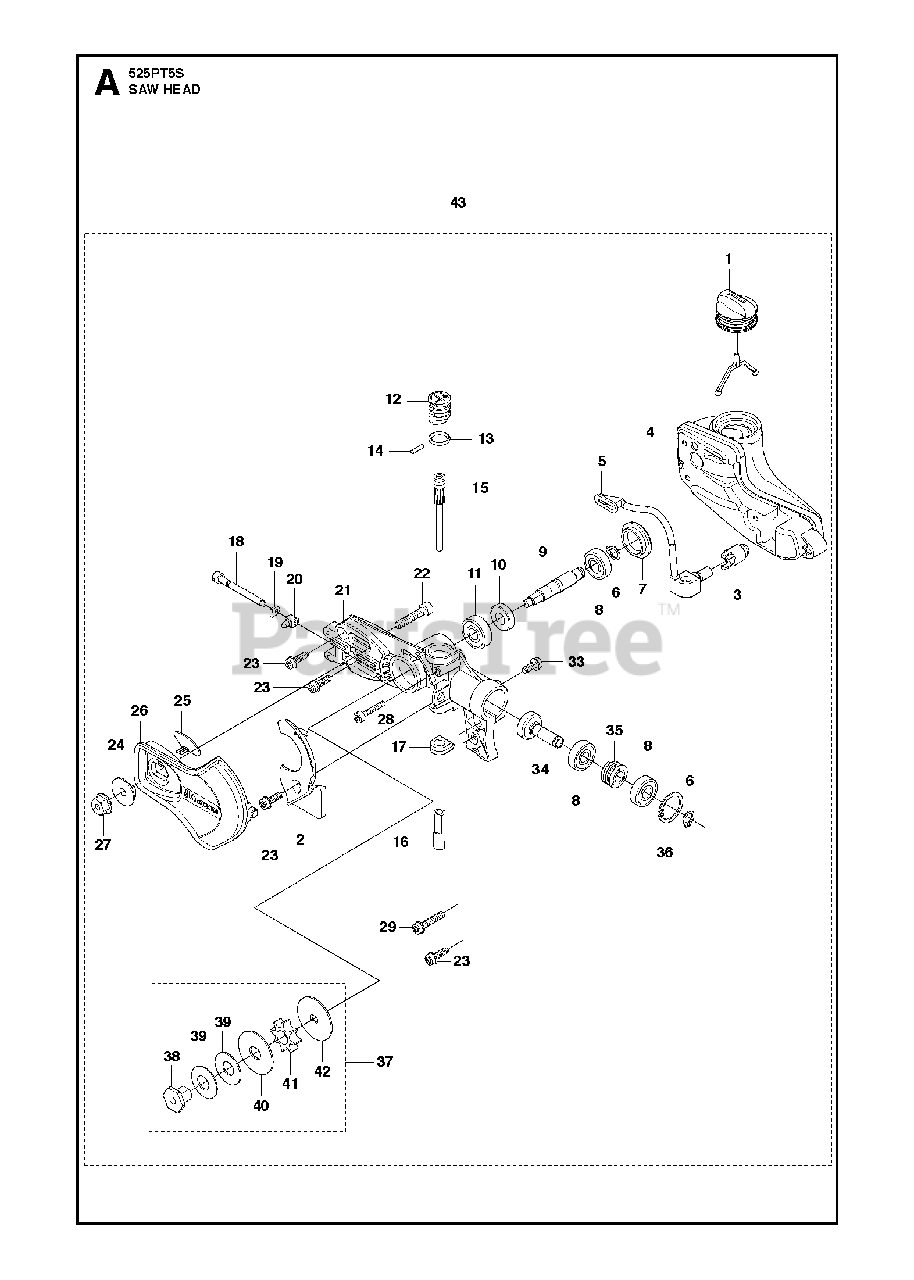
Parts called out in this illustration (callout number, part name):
1	RP TANK CAP ASSY
2	COVER
3	OIL SCREEN
4	OIL TANK
5	OIL HOSE
6	RETAINING RING
7	COVER
8	BALL BEARING
9	SHAFT
10	GEAR WHEEL
11	BALL BEARING
12	KNOB
13	O-RING
14	NEEDLE ROLLER
15	PISTON PUMP
16	PUMP CYLINDER
17	FASTENER
18	SCREW
19	NUT
20	PAWL
21	GEAR HOUSING
22	SCREW IHSCM
23	SCREW
24	BUSHING
25	RUBBER
26	COVER
27	HEXAGON NUT FLANGED
28	SCREW ITXSCM
29	SCREW
33	SCREW
34	PINION
35	WORM GEAR
36	RETAINING RING
37	SPROCKET KIT 1/4"
37	SPROCKET KIT 3/8"
38	NUT
39	DISC SPRING
40	WASHER
41	SPUR SPROCKET FOR 1/4" CHAIN
41	SPROCKET 3/8"
42	WASHER
43	POLE SAW HEAD HUSQVARNA 1/4"
43	POLE SAW HEAD HUSQ 3/8"
